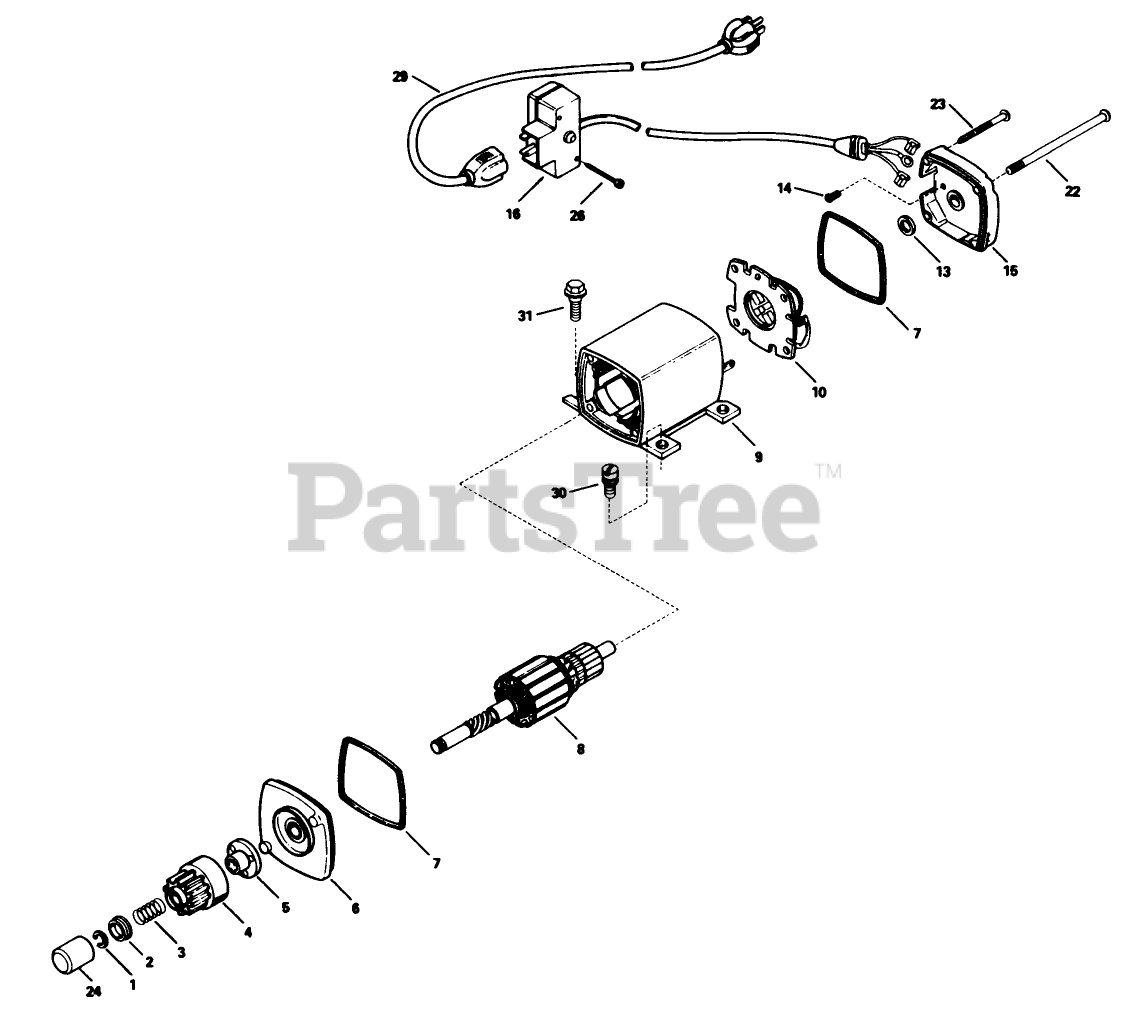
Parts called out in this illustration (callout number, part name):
1	Ring-Retainer
2	Retainer-Spring
3	Spring-Anti Drift
4	Gear
5	Nut-Engaging
6	Cap Assembly-Cap End (Incl. Ref. #7)
7	O-Ring
8	Armature
9	Housing Assy.
10	Card ASM
13	Washer-Thrust
14	Screw-Ground
15	Cap Assembly (Incl. Ref. #7)
16	Box Assembly-Switch (Incl. Ref. #26)
22	Bolt-Case
23	Screw-Ground
24	Cover-Dust
26	Screw
29	Cord-Extension
30	Screw
31	Screw (1/4-20x1/2)
